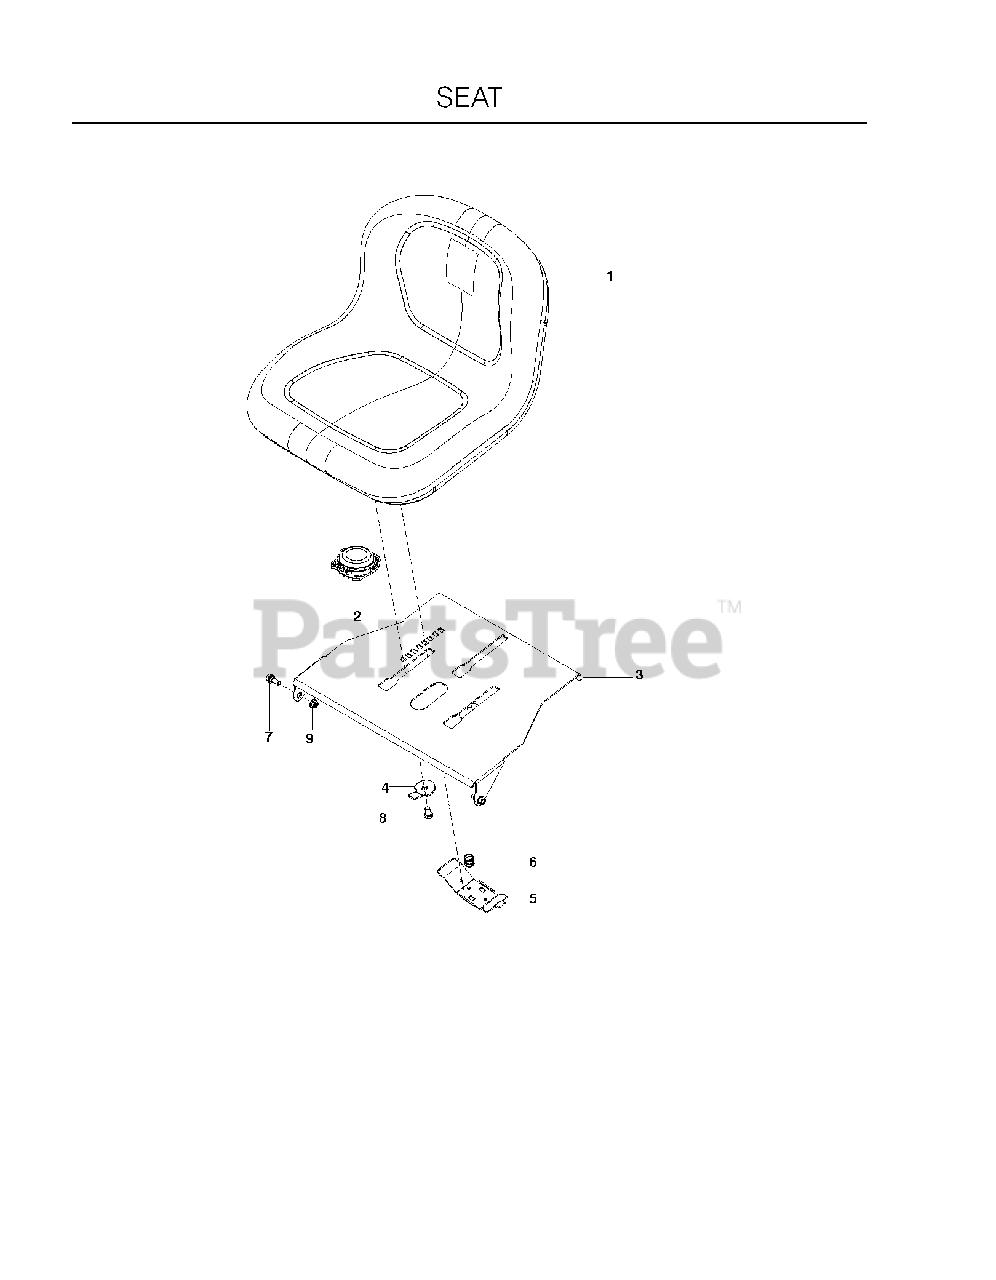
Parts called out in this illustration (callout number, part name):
1	SEAT,BLACK W/ARMREST PROVISION
2	SWITCH, SEAT N/C
3	PLATE, SEAT, YLW
4	STOP, SEAT, BLACK
5	HANDLE.SLIDE.SEAT.TEX.BLACK
6	SPRING.LATCH.SEAT.TEX
7	BOLT, SHOULDER
8	HCS 3/8-16 X 5/8 GR 5 ZD
9	5/16-18 NYLOC FLANGE NUT
